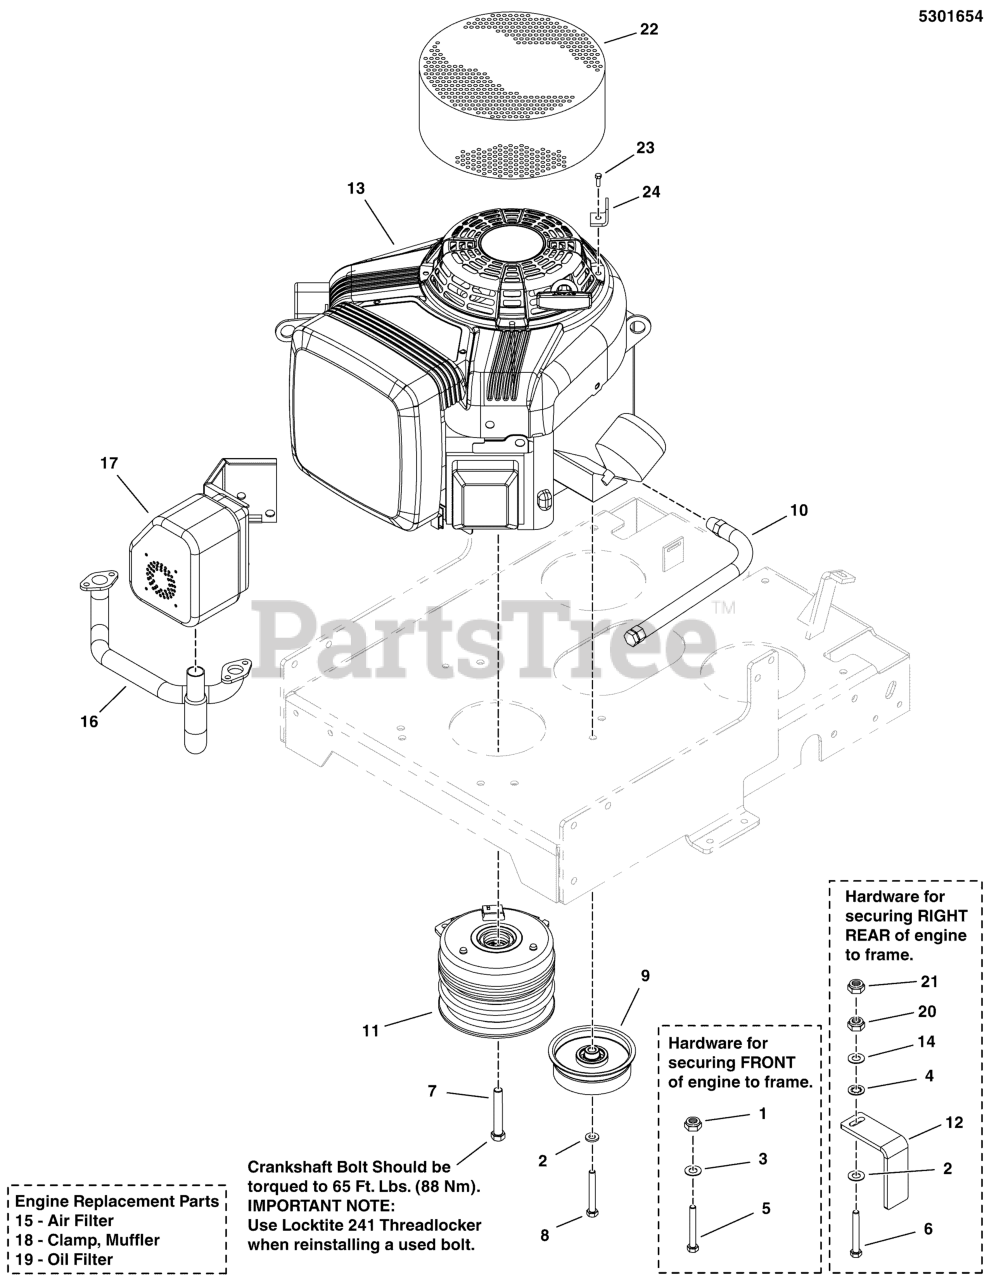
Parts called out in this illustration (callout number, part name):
1	NUT, 5/16-18 HEX NYLON LOCK
2	WASHER, 5/16 GD.9 FLAT
3	WASHER, 5/16" SAE
4	WASHER, 5/16" INT. TOOTH LOCK
5	BOLT, 5/16-18 X 1-1/2" GD5 YZ
6	BOLT, 5/16-18 X 1-3/4 GD5 YZ
7	BOLT, CRANKSHAFT, 7/16-20 X 3, GD8
8	BOLT, 5/16-18 X 2-1/2" GD5 YZ
9	PULLEY, IDLER, SINGLE FLANGE
10	HOSE, OIL DRAIN
11	CLUTCH, WARNER, 125 ft lbs - 1"
12	ANCHOR, CLUTCH - BLK
13	ENGINE, BRIGGS, VANGUARD
14	WASHER, 5/16 LOCK CZ
15	AIR FILTER
16	MANIFOLD, EXHAUST
17	MUFFLER, EXHAUST
18	CLAMP, MUFFLER ASSEMBLY
19	OIL FILTER
20	NUT, 5/16-18 HEX
21	NUT, 5/16-18 HEX NYLOCK FLANGE
22	GUARD, DEBRIS ASSY
23	SCREW, TAPPING HEX
24	BRACKET, MOUNTING
